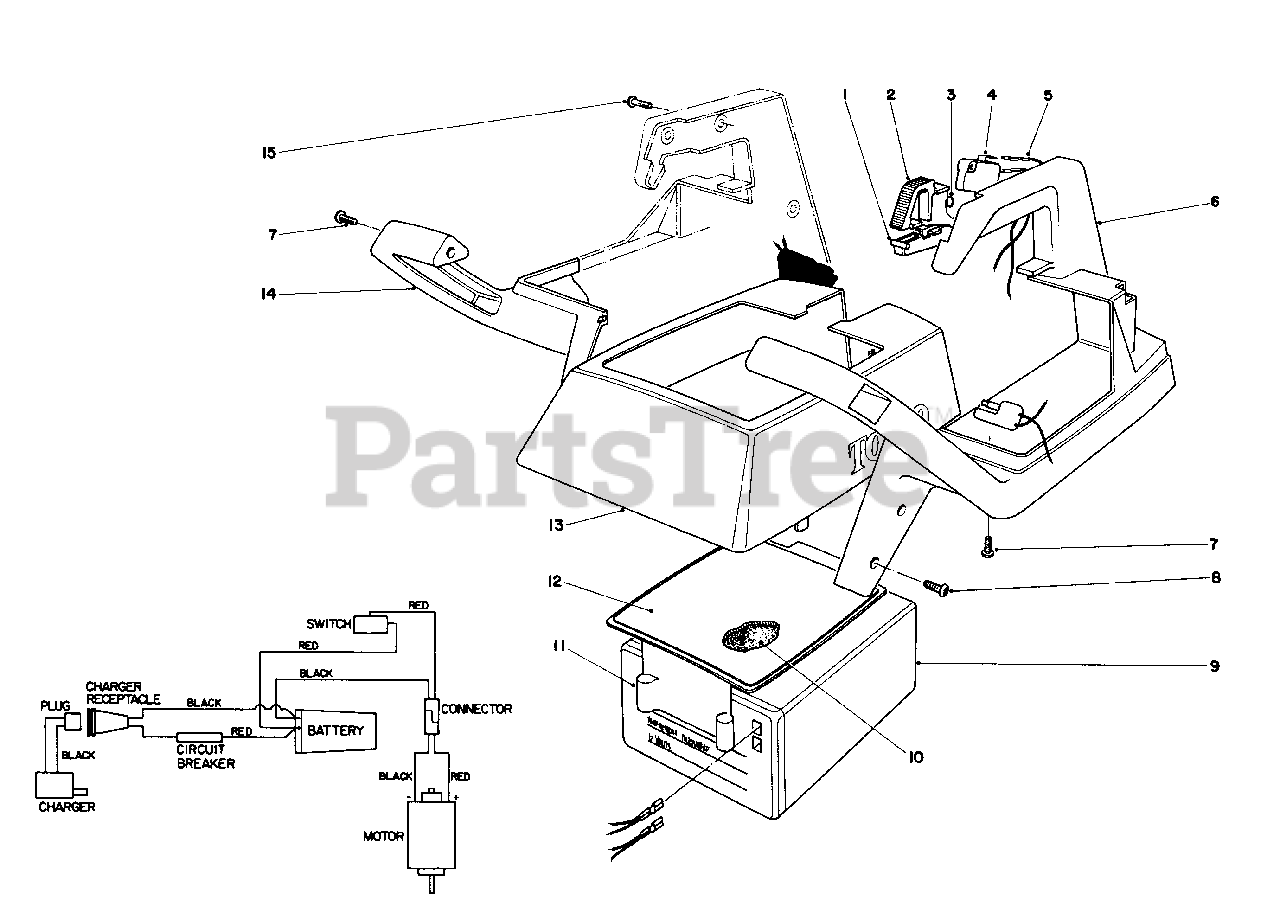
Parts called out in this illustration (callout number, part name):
2	Release-Trigger
5	Wiring Harness
6	Handle & Battery Case L.H.
7	Screw
8	Screw-Self Tapping
10	Pad-Foam
11	Panel-Control
12	Decal-Control Panel
14	Handle & Battery Case R.H.
